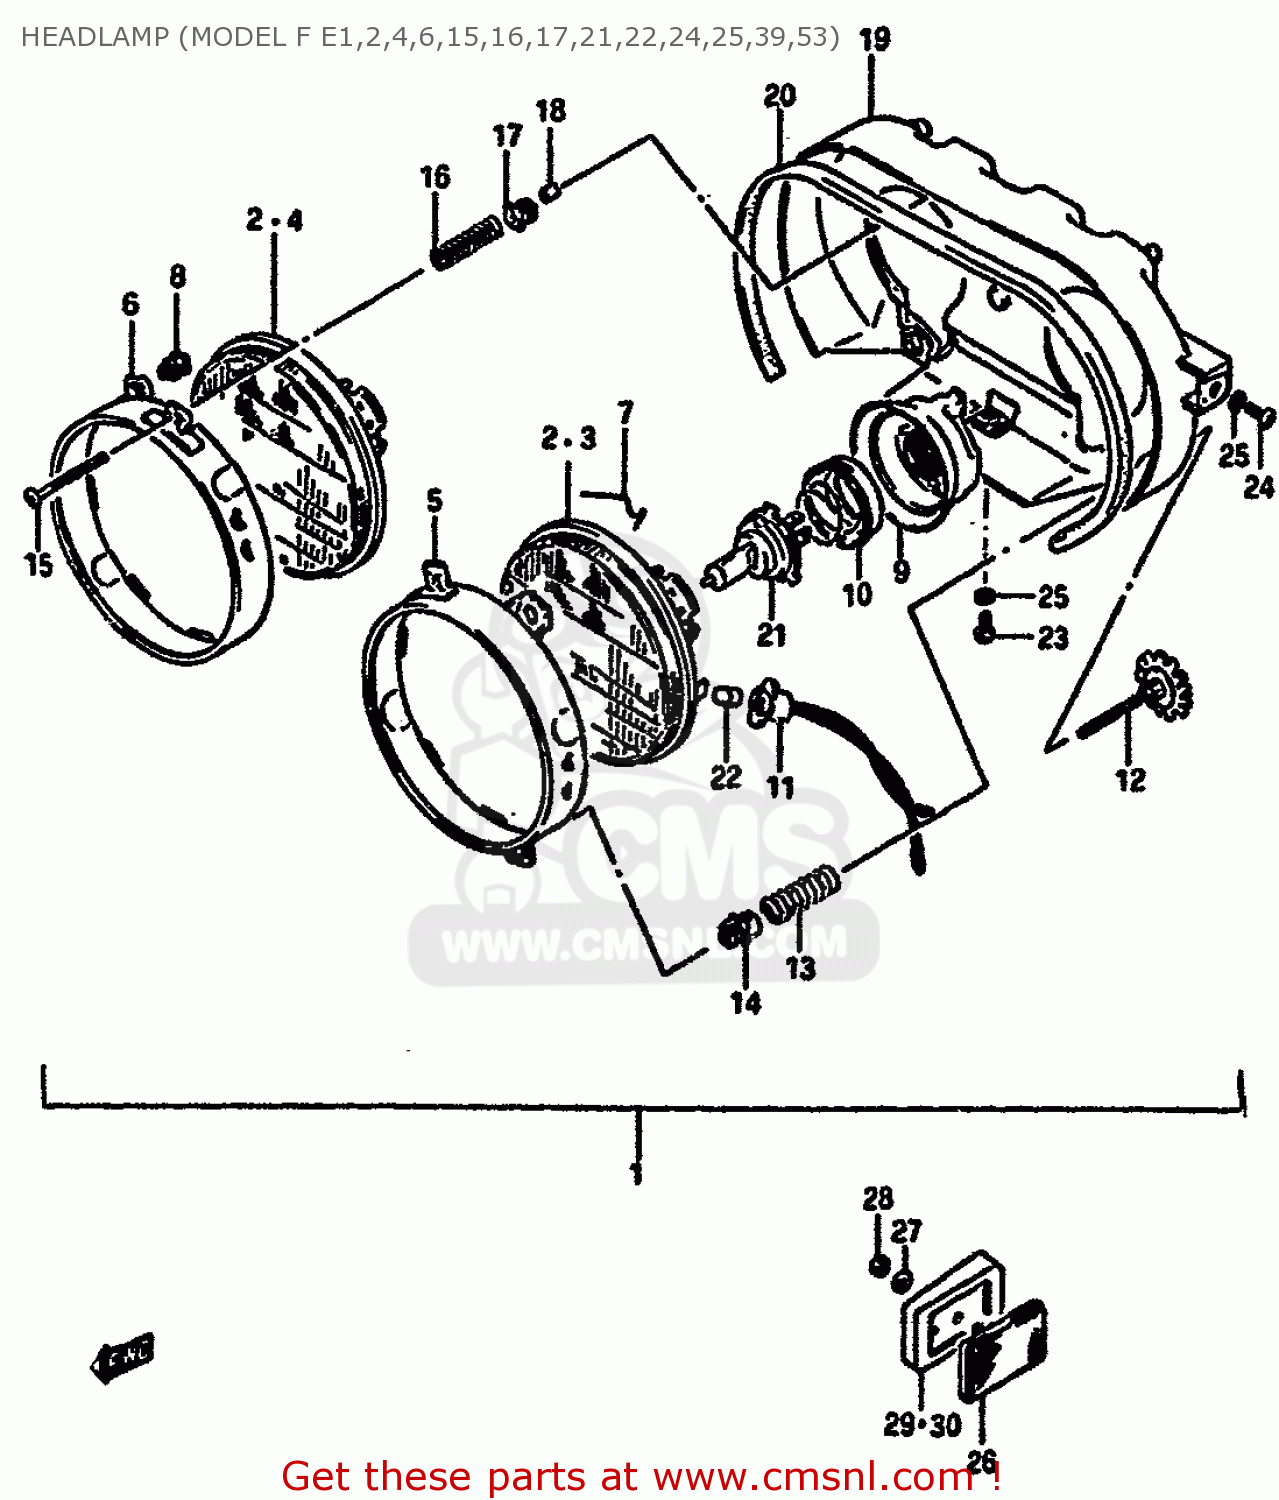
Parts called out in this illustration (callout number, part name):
1	HEADLAMP ASSY
2	UNIT
3	UNIT,LH
4	UNIT,RH
5	RING,RETAINING,LEFT
6	RING,RETAINING,RIGHT
7	SPRING
8	SCREW,SPHERICAL
9	COVER,SOCKET
10	SETTING,BULB
11	SOCKET
12	SCREW,ADJUSTER
13	SPRING
14	NUT
15	SCREW,ADJUSTER
16	SPRING
17	NUT
18	CAP,SCREW
19	HOUSING
20	GASKET (NAS)
21	BULB(12V45/40W)
22	BULB(12V4W)
23	SCREW
24	SCREW
25	WASHER,LOCK
26	REFLEX REFLECTOR, FRONT SIDE
27	WASHER,5MM
28	NUT ,5MM
29	SPACER,FRONT SIDE,REAR,RIGHT
30	SPACER,FRONT SIDE,REAR,LEFT
